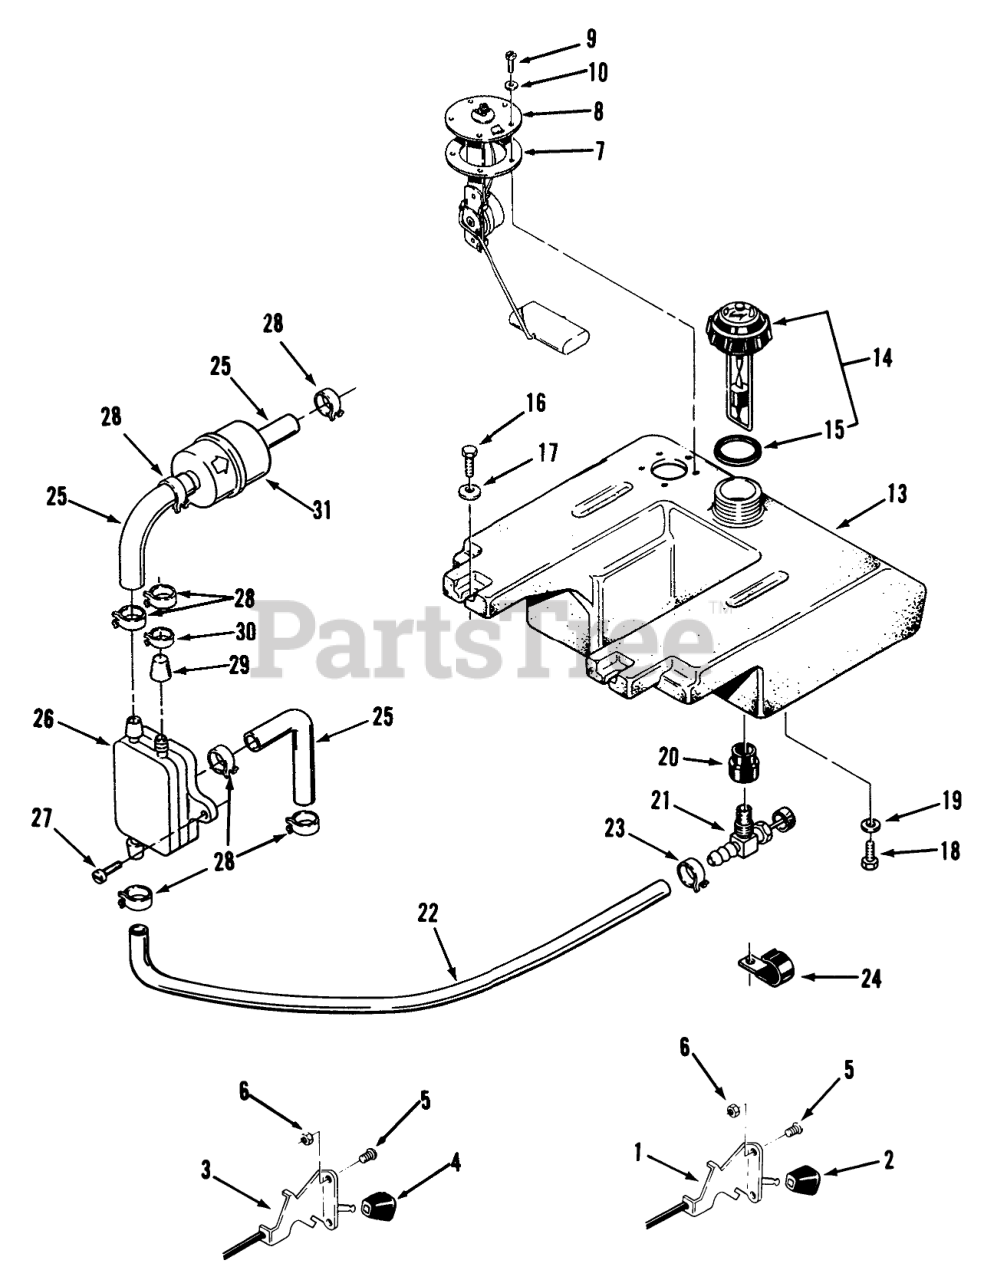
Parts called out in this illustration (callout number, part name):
1	CONTROL-THROTTLE
3	CONTROL-CHOKE
4	NUT-HEX PALNUT
13	TANK-FUEL
14	ASSY-GAUGE CAP
21	VALVE-FUEL
